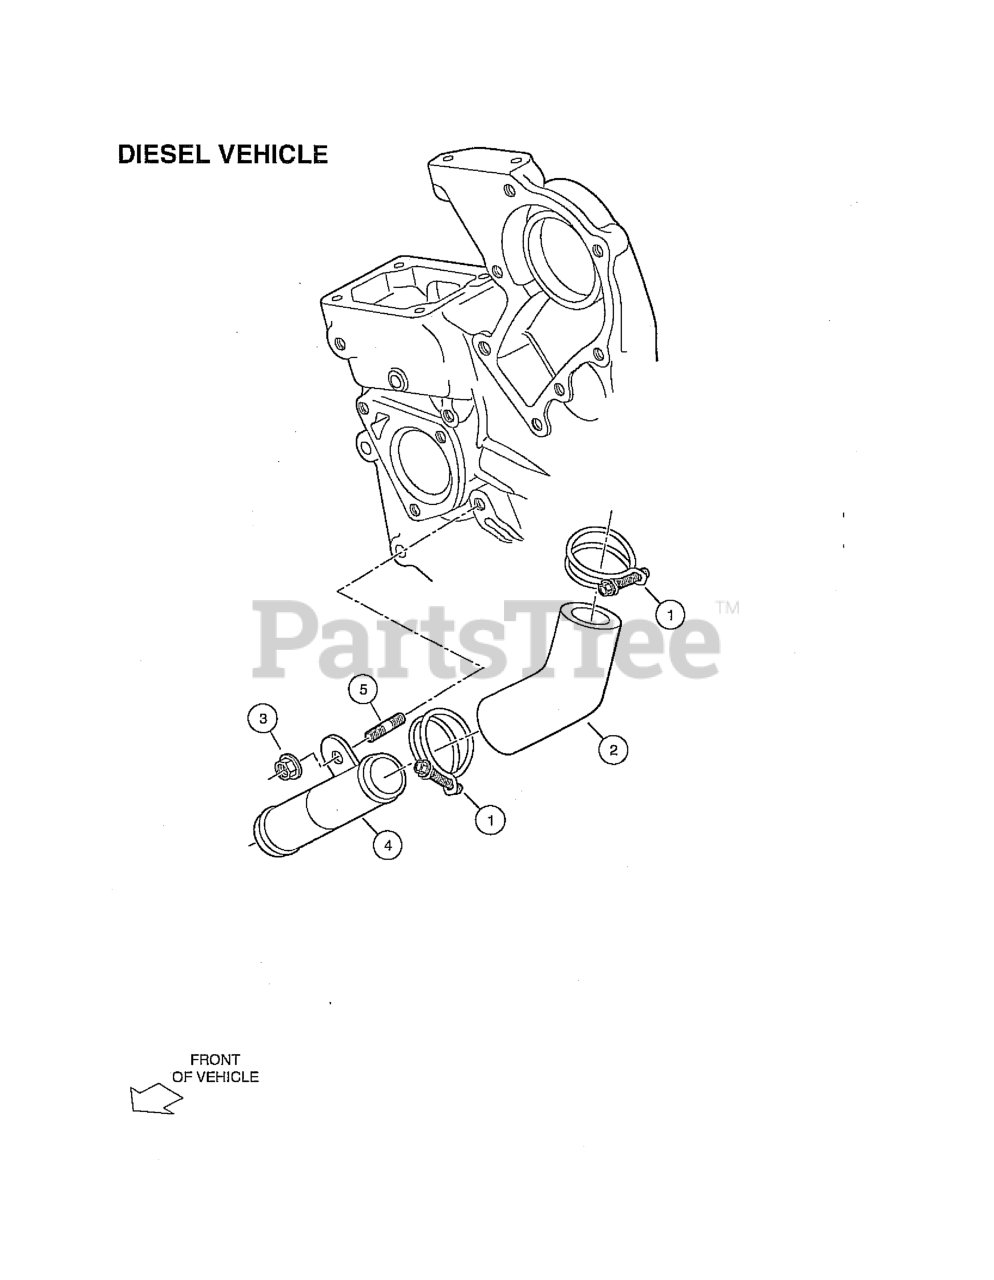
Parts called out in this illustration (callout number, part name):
1	BAND, PIPE, WITH NUT
2	PIPE, WATER, BENT
3	NUT, FLANGE, M6
4	PIPE, WATER, BENT
5	STUD, M6X15
